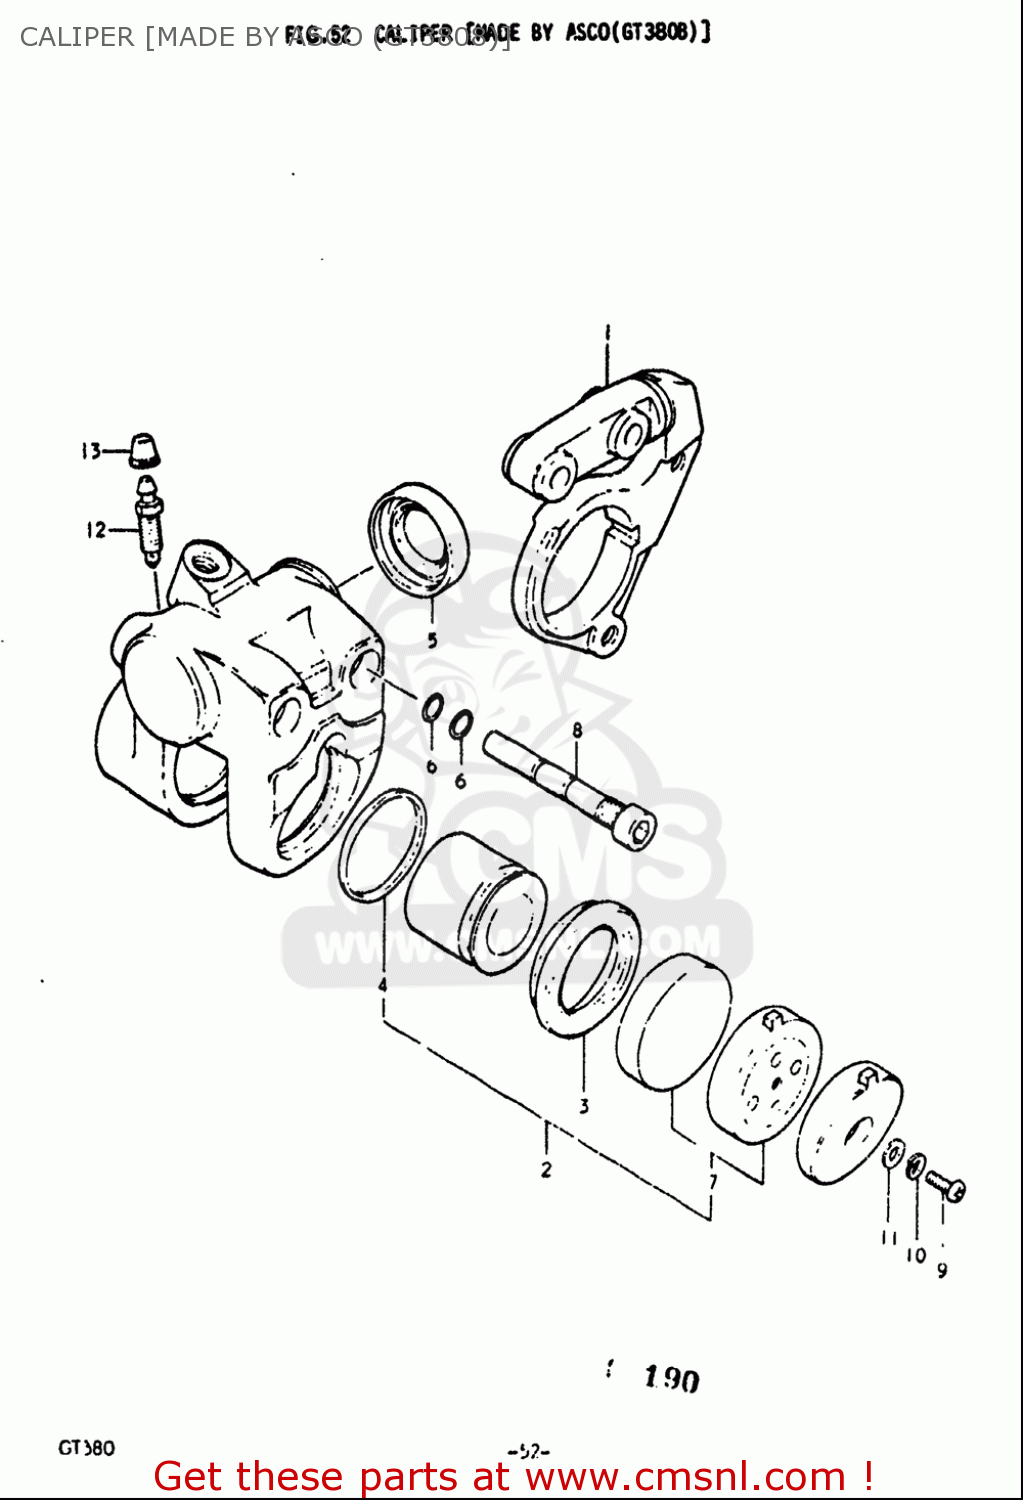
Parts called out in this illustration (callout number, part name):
1	HOLDER,CALIPER
3	BOOT,PISTON
4	SEAL,PISTON
5	BOOT,HOLDER
6	O RING,AXLE CALIPER
8	AXLE,CALIPER
9	SCREW
10	WASHER,LOCK
11	WASHER
12	BLEEDER
13	CAP,BLEEDER PLUG
